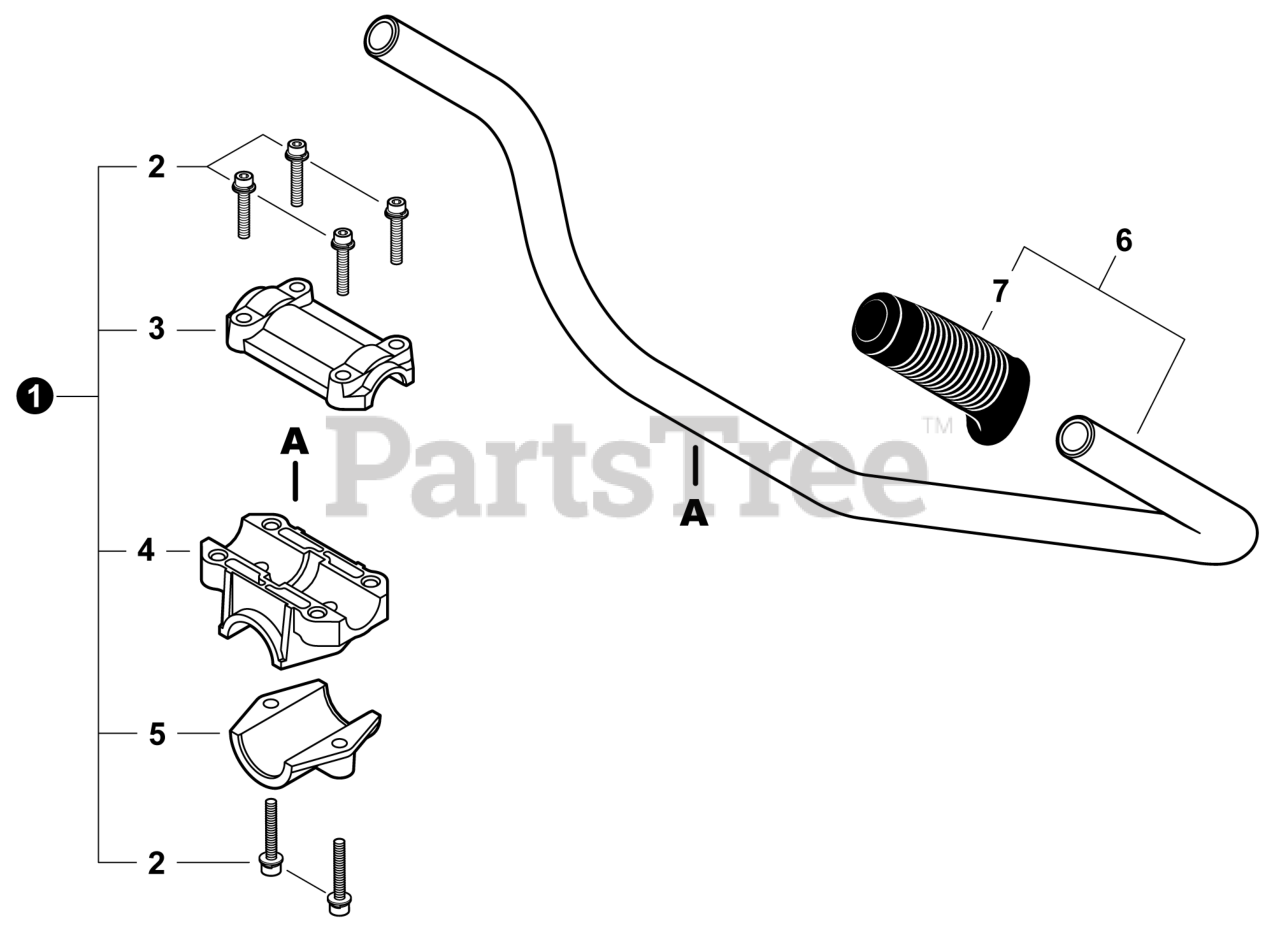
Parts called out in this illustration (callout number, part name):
1	BRACKET KIT, HANDLEBAR
2	BOLT, TORX 5x25
3	BRACKET, UPPER
4	BRACKET, LOWER
5	BRACKET, MOUNTING
6	HANDLE ASSY
